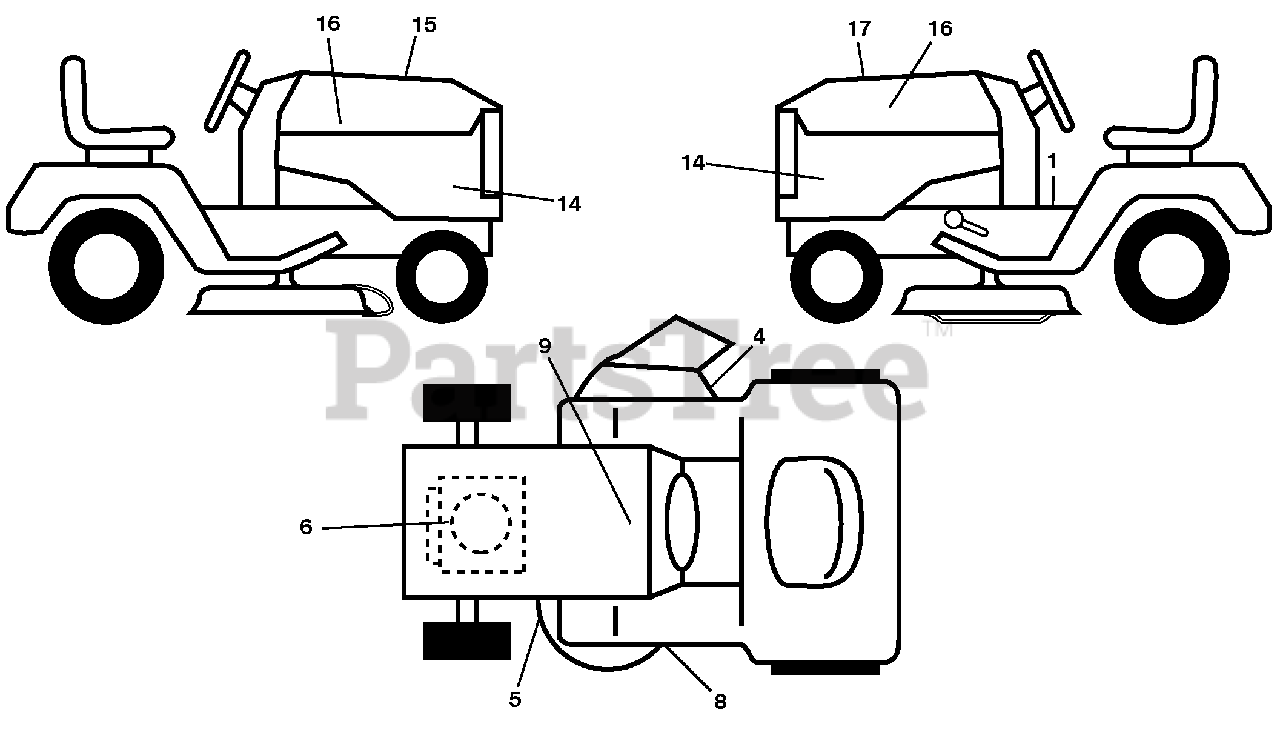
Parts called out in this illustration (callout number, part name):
1	Decal, Warning
4	Decal, Mower Warning
5	Decal, Caution
6	Decal, Eng.
8	Decal, Mower Sch.
9	Decal, Battery Dnge/Poi
14	Decal, Panel Side
15	Decal, Cust. Resp.
16	Decal, Hood Logo
17	Decal, Replacement
